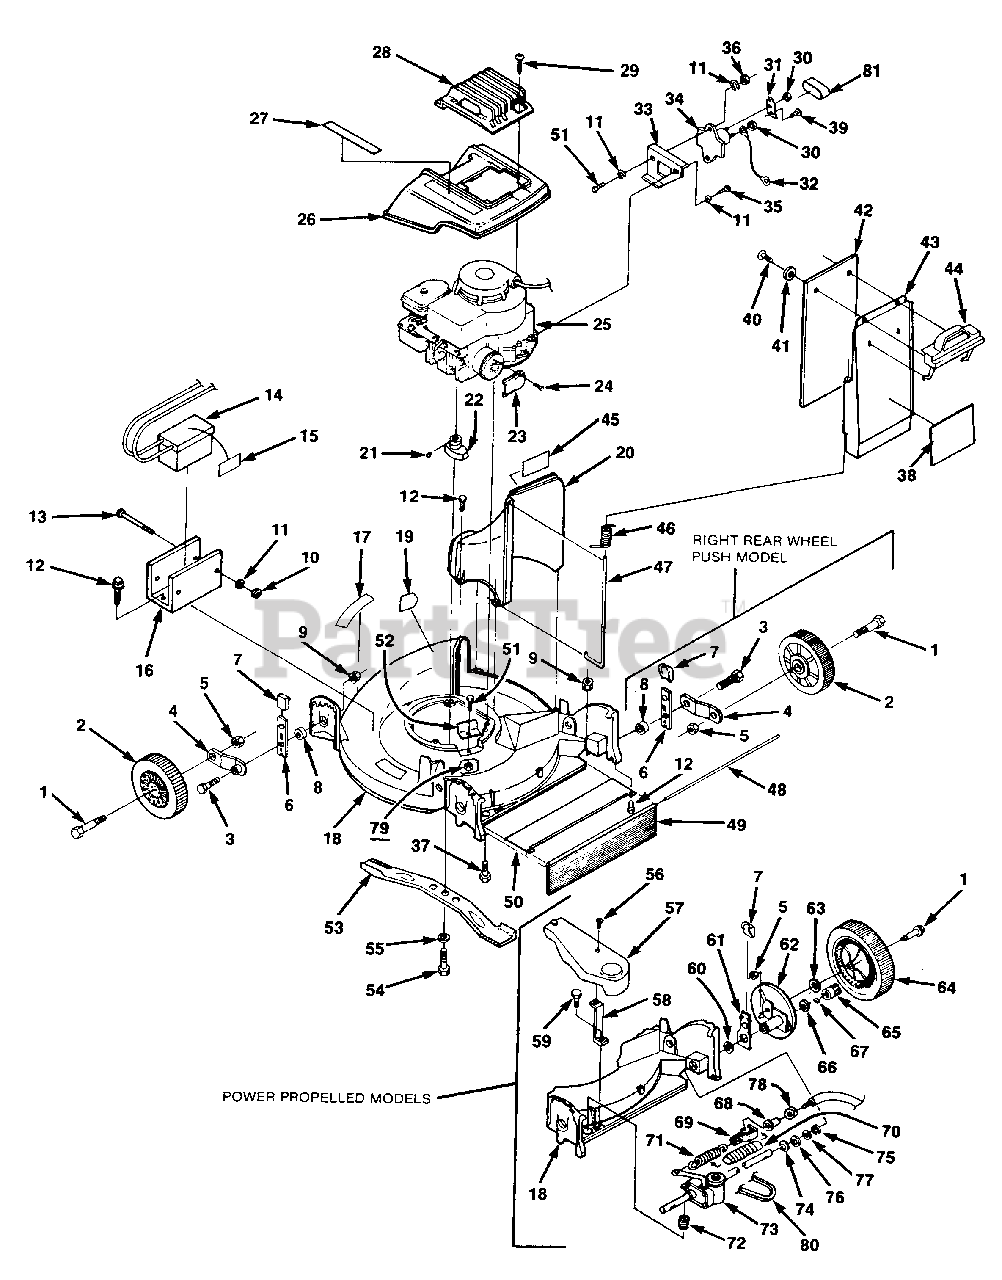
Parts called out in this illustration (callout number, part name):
1	BOLT- Axle
2	WHEEL & TIRE ASSY.
4	WHEEL- Adjuster arm
6	SPRING
7	KNOB
9	NUT- Flange
10	NUT
11	WASHER
12	SCREW
13	BOLT
14	BATTERY- 6 Volt
15	DECAL- Battery
16	HOLDER- Battery
17	DECAL- Product ID
18	DECK ASSEMBLY
19	DECAL- Warning
20	CHUTE
22	ADAPTER- Blade
23	DEFLECTOR
25	ENGINE- 3.5
26	COWLING- Engine
27	DECAL- Engine
30	NUT-
31	TERMINAL- Adaptor
32	LEAD- Electrical
33	BRACKET
34	RELAY
35	SCREW
36	NUT- 1/4-20 hex
37	BOLT- Engine Mounting
38	DECAL- Door
39	SCREW #10-16 x 1/2
41	WASHER
42	DAMP- Flap
43	DOOR- Chute
45	DECAL- 4 HP
46	SPRING
48	ROD- Drag flap
49	FLAP- Drag
50	COVER
51	SCREW
52	COVER- Belt opening
56	SCREW
57	COVER- Drive
58	SUPPORT
59	SCREW
60	SPACER
61	SPRING
62	DRIVE WHEEL SUPPORT ASSY.
63	WASHER
64	WHEEL & TIRE
65	PINION (R.H.)
66	WASHER
67	PAWL- Pinion
68	CONNECTOR
69	CLEVIS
70	COVER- Spring
71	SPRING- Extension
72	SPRING- Compression
73	GEAR REDUCER ASSY.
74	RING- Eaton
75	WASHER
76	WASHER
78	NUT
80	BELT
